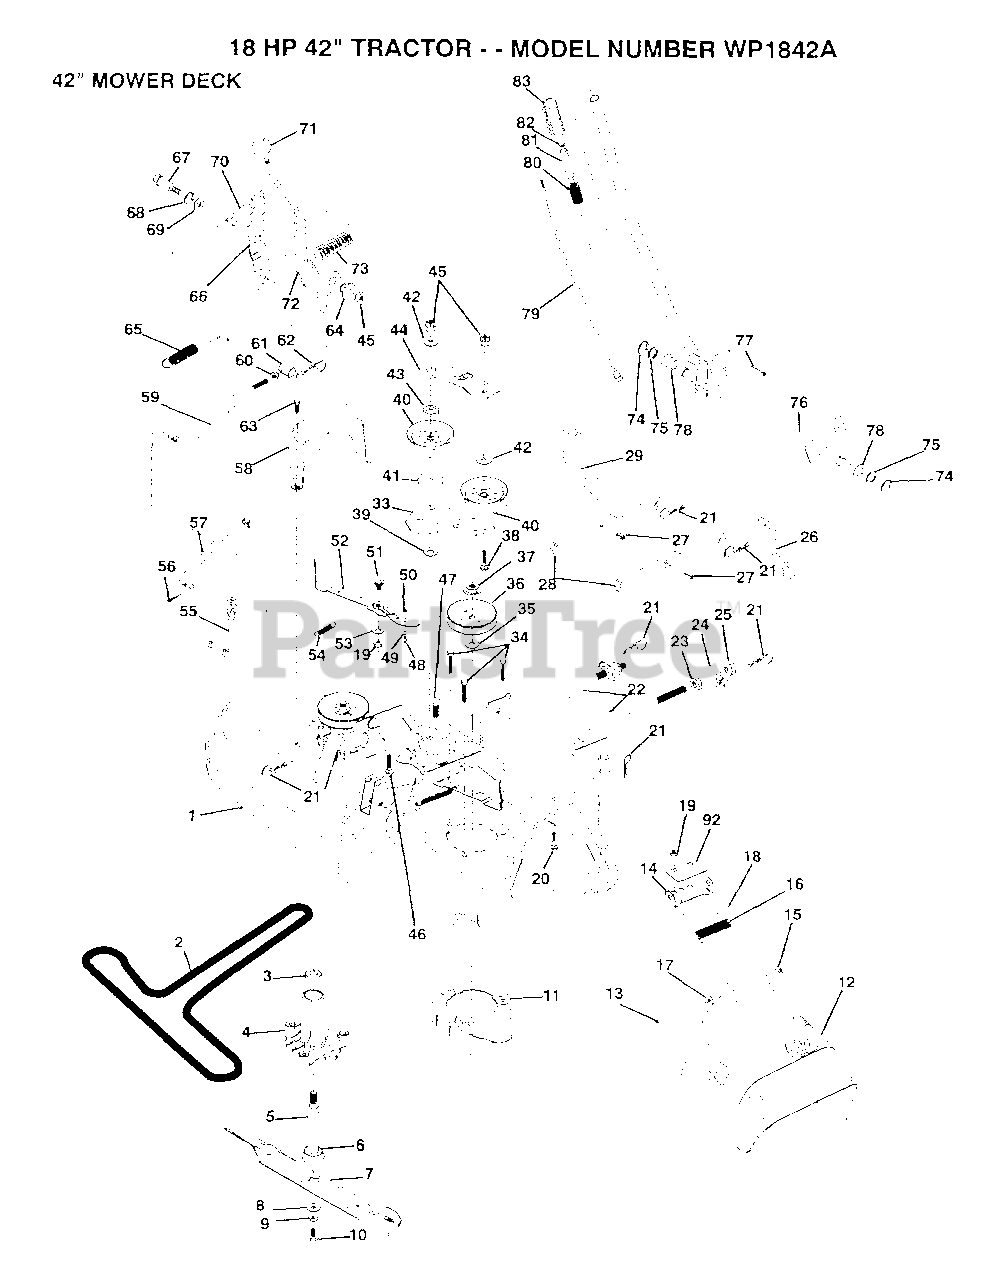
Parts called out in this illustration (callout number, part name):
2	BELT-V.92.4.MWR
3	BEARING
4	HSG ASM MANDREL
6	BEARING.BALL
8	WASHER BLADE
10	BLADE BOLT
12	DEFLECTOR.SHIELD
13	HINGE ROD
14	DEFLECTOR BRKT
15	NUT PUSH M
16	SPRING TORSION
17	WASHER
18	CAP-SLEEVE LT
20	BOLT
22	LINK.FRONT
23	NUT
24	TRUNION
25	NUT.LK.W/WSH.1/2.
26	LIFT LINK RH
27	"PIN,SPRING"
29	LINK LIFT LH
33	IDLER ARM
35	WASHER
38	BOLT
39	HARDENED WASHER
40	FLAT IDLER PULLEY
41	SPACER RETAINER
42	WASHER GT
43	RETAINER SPACER
44	IDLER ARM STIFF
46	BOLT CARRIAGE
47	XMAS TREE FASTNER
48	SHOULDER BOLT
50	LOCKNUT
52	BRAKE PAD ARM ASM
53	HARD SMALL WASHER
54	SPRING EXTENSION
55	PIVOT ROD
57	CLUTCH ROD SECOND
60	NUT
61	TRUNION
62	RETAINER M
63	SCREW LT
64	BUSHING
65	RETURN SPRING
66	CLUTCH ARM SECOND
67	SHOULDER BOLT
68	RING
69	WASHER
70	SPRING KEEPER
75	WASHER
76	LIFT SHAFT ASM
77	PIN-GROOVE LT
78	NYLON BEARING
83	GRIP
92	STIFFENER BRKT
